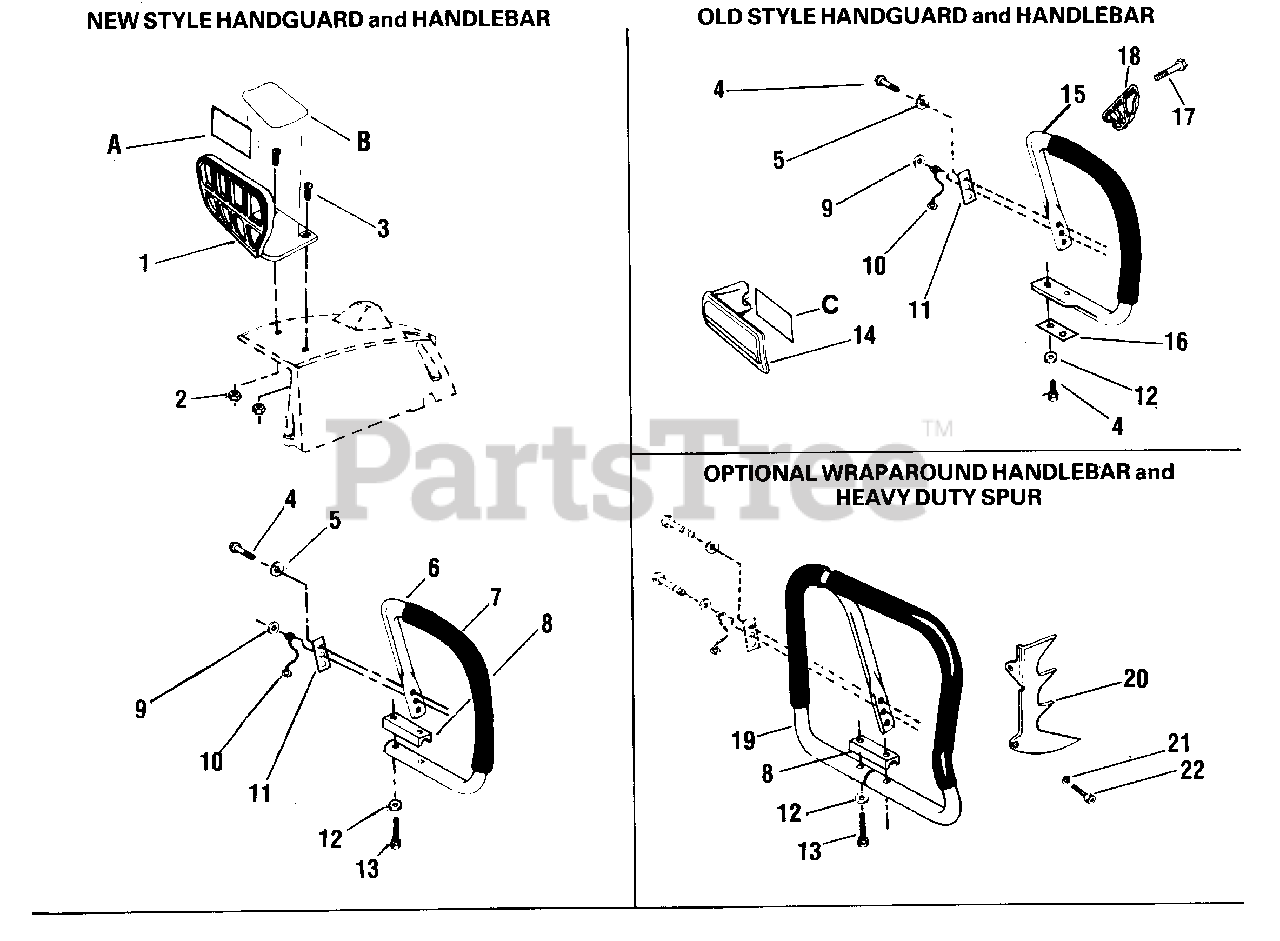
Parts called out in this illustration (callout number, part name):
1	andguard
3	Screw - 10 - 24 x 1/2
4	Screw - 1/4 - 20 x 3/4
5	Lockwasher
6	Handlebar - Flushcut
7	Kit - Handlebar Grip
8	Adaptor - Handlebar
9	Washer - Flat
10	Lead Ground
11	Handlebar Brace - Rear
12	Washer - Conical
13	Screw - 1/4 - 20 x 1-3/8
14	Handguard
15	Handlebar - Flashcut
16	Handlebar - Brace Bottom
17	Screw - Handguard
18	Cap - Handguard
19	Kit-Wraparound Handlebar
20	Spur - Heavy Duty
21	Lockwasher - Spur
22	Screw - Spur
A	Decal - Starting Instructions
B	Decal - Kickback
C	Decal - Handguard
